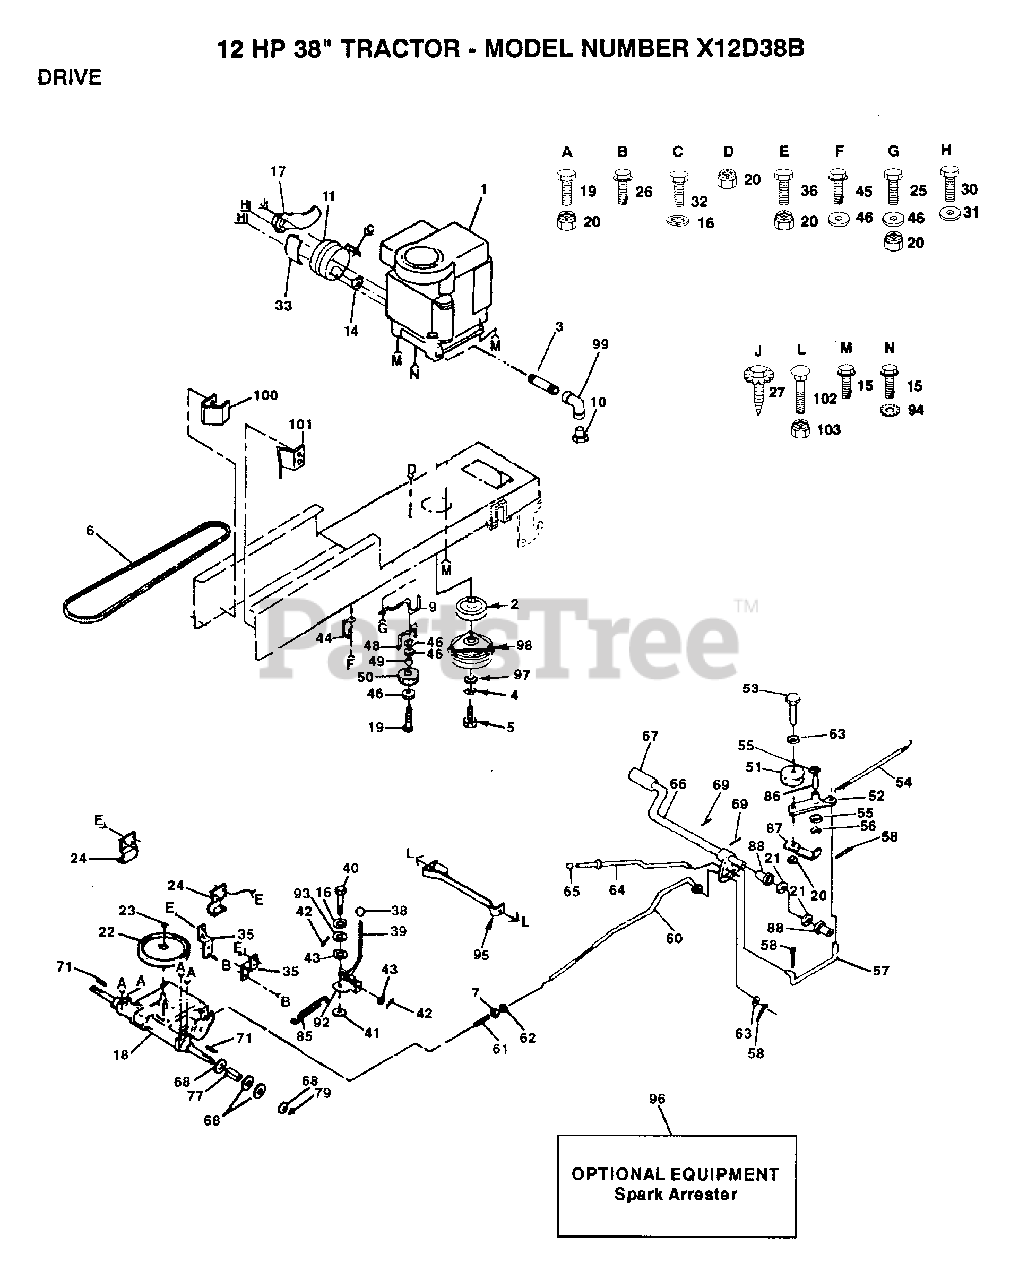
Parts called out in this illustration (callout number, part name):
3	PIPE NIPPLE
4	LOCKWASHER
6	BELT-V.90.0.GD.DR
7	NUT
8	KEEPER.BELT.ENG.L
11	MUFFLER LTV
15	SCREW LT
16	LOCKWASHER
17	DEFLECTOR MUFFLER
19	BOLT
21	WASHER LT
22	PULLEY TRANS
24	BRACKET LT
25	BOLT
26	SCREW
30	"BOLT,HEX"
31	WASHER T
32	BOLT
33	SHIELD HEAT LTV
35	STRAP TORQUE
38	KNOB T (1/2-HOLE)
39	ROD SHIFTER
41	WASH-SHFT PLT LT
42	PIN COTTER 1/8
43	WASHER
45	SCREW
46	WASHER
48	BELT KEEPER LT
49	SPACER T
50	PULLEY.IDLER.FLAT
52	ARM IDLER
54	"SPRING, RETURN LT"
55	WASHER LT
56	KLIP RING
57	"LINK, CLUTCH T"
58	COTTER PIN
61	SPRING ROD LT
62	NUT
63	WASHER
64	PARKING BRAKE ROD
65	PLUNGER CAP T
67	PEDAL COVER T
68	WASHER
71	SQUARE KEY
77	SPACER LT
79	E-RING LT
86	"LY, BEARING"
87	RETAIN BELT
88	NYLON BEARING
92	PLATE SHIFT LT
93	WASHER LT
94	LOCKWASHER
97	WASHER
99	ELBOW
100	"KEEPER,BELT LH T"
101	"KEEPER,BELT RH T"
102	BOLT
